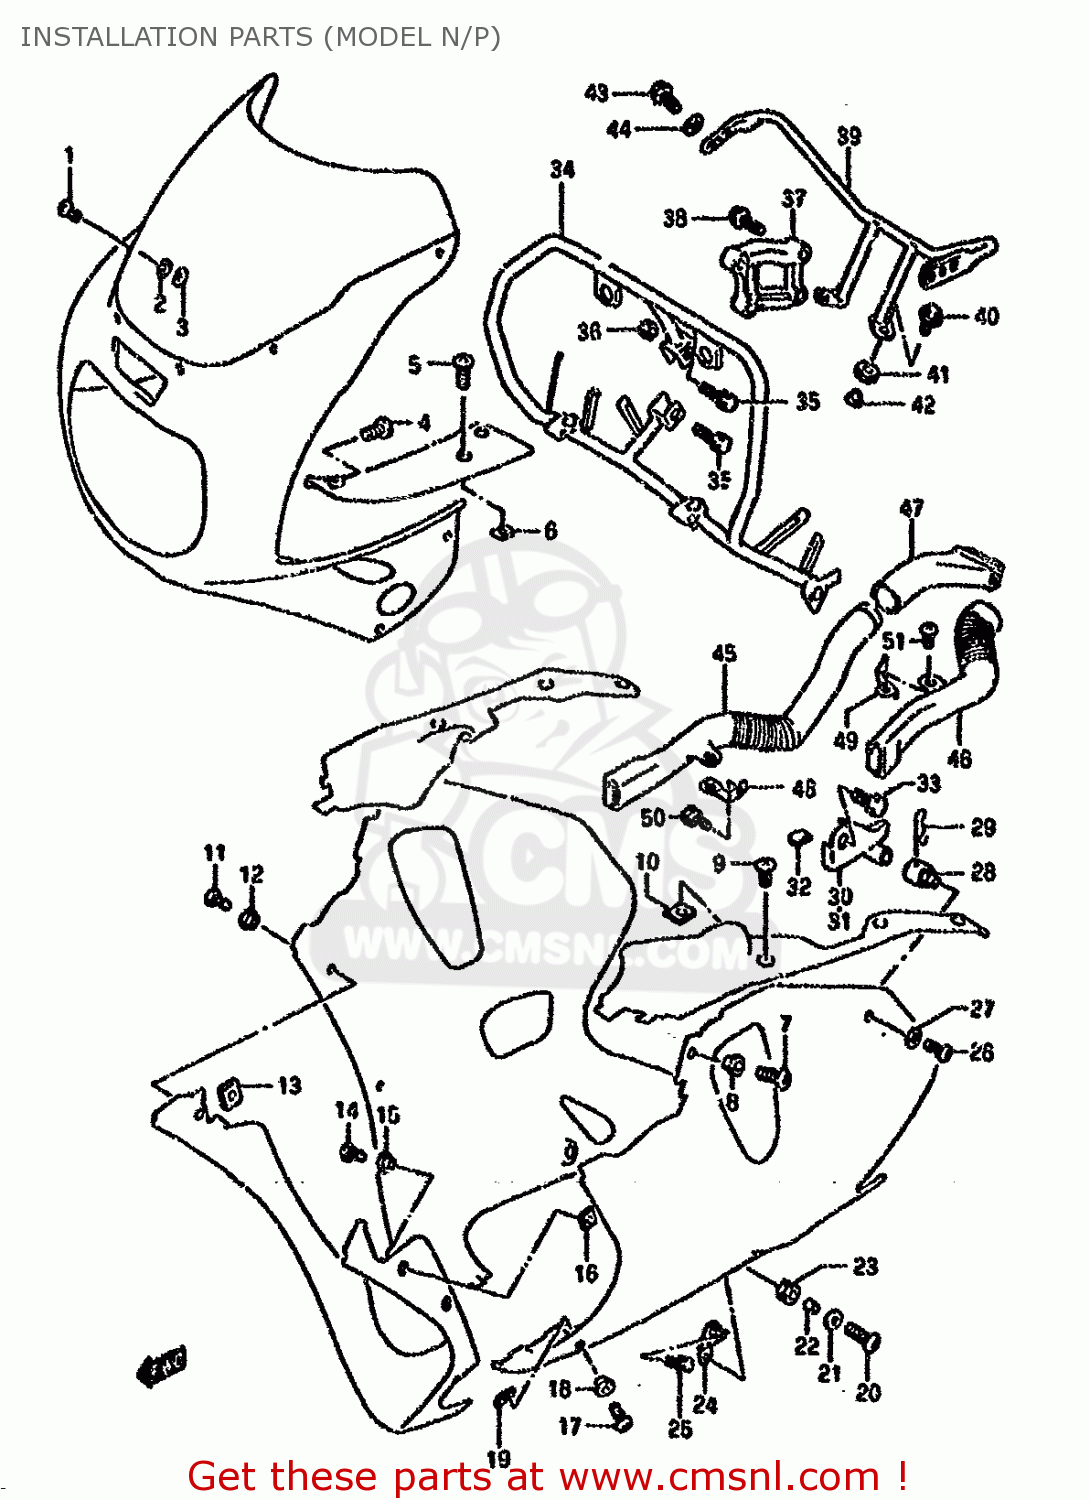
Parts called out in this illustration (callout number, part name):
1	PIN,WINDSCREEN
2	CUSHION
3	NUT
4	SCREW, FRONT & REAR
5	SCREW
6	NUT
7	SCREW(5X18)
8	WASHER(5.2X14X1.5)
9	SCREW
10	NUT
11	SCREW(5X18)
12	WASHER(5.2X14X1.5)
13	NUT,RH & CTR UNDER COWLING
14	SCREW
15	WASHER(5.2X14X1.5)
16	NUT
17	SCREW(5X18)
18	WASHER(5.2X14X1.5)
19	NUT,RH & CTR UNDER COWLING
20	SCREW(6X25)
21	WASHER(6.5X18X1)
22	SPACER (6.1X9X10)
23	CUSHION
24	BRACKET,UNDER COWLING
25	BOLT
26	SCREW(6X20)
27	WASHER
28	PLUG,UNDER COWL FTG,CTR
29	PIN,UNDER COWLING FITTING PIPE
30	BRACE,UNDER COWLING,UPPER
31	BRACE,UNDER COWLING,UPPER
32	CUSHION,UPR BRACE
33	BOLT, BRACKET (6X12)
34	BRACE,COWLING
35	BOLT,BRACE (8X30)
36	NUT 8MM
37	BRACE,COWLING CTR
38	BOLT,BRACE (8X40)
39	BRACE,RR VIEW MIRRORR
40	BOLT 6X20
41	CUSHION
42	WASHER
43	SCREW(6X12)
44	WASHER(6.2X19X1.5)
45	PIPE,AIR INTAKE FR,R
46	PIPE,AIR INTAKE FR,L
47	PIPE,AIR INTAKE RR,R
48	JOINT,AIR INTAKE
49	BRACKET,AIR INTAKE,LEFT
50	BOLT, BRACKET (6X12)
51	SCREW 6X12
